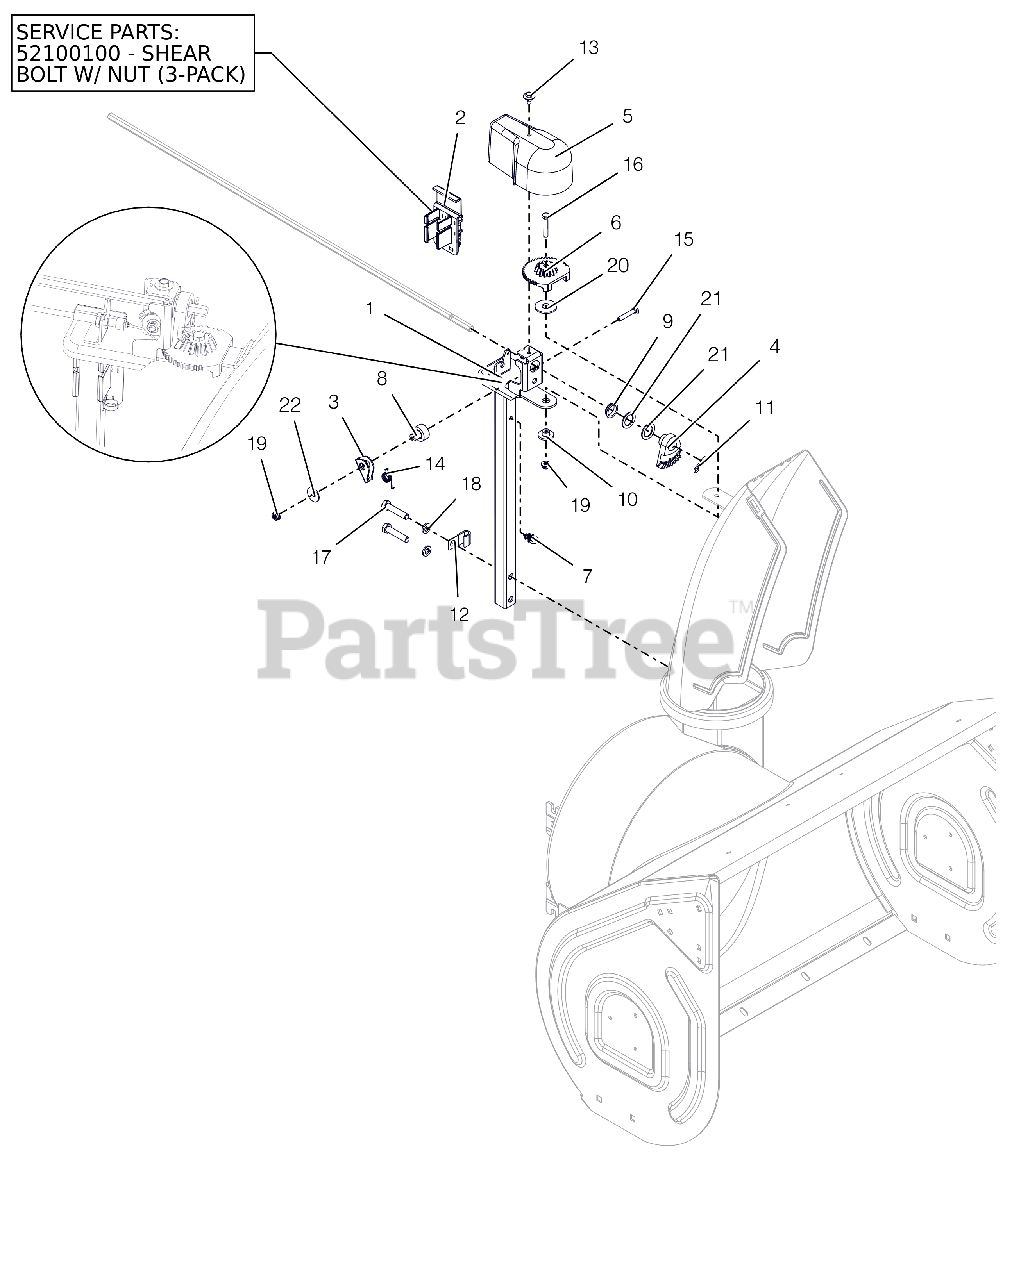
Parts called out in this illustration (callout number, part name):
1	PEDESTAL, CHUTE - QUICK STICK
2	HOLDER W LARGE SHEAR BOLT /NUT
2	SHEAR BOLT SERVICE ASSEMBLY
3	ARM, LOCKING
4	GEAR, CHUTE-ACTUATION
5	COVER, CHUTE GEAR
6	GEAR, CHUTE
7	CLIP, CABLE GUIDE
8	BUSHING, LOCK ARM
9	BUSHING, POLYLINER-.75 SNAPIN
10	BSHG-FLG .265X.477X.375X1.00
11	PIN-HAIR INT .08X.18X1.18 YWZC
12	J-CLAMP
13	SCR-TAP .25-20X.50 LGHWH TR YZ
14	SG-TORS
15	@BLT-RDHDSQNK .25-20X1.50 G5YZ
16	@BLT-HEX .25-20X1.50 GR5 YWZC
17	@BLT-HEX .38-16X1.75 GR5 YWZC
18	@WSHR-LK .38X.094 REG YWZC
19	@NUT-LK-CTR-FLG .25-20 YWZC
20	WSHR-FLT-NYL .515X1.375X.093
21	WSHR-FL-STL.754X1.125X.062YWZC
22	WSHR-FL-STL .281X1.000X.063
